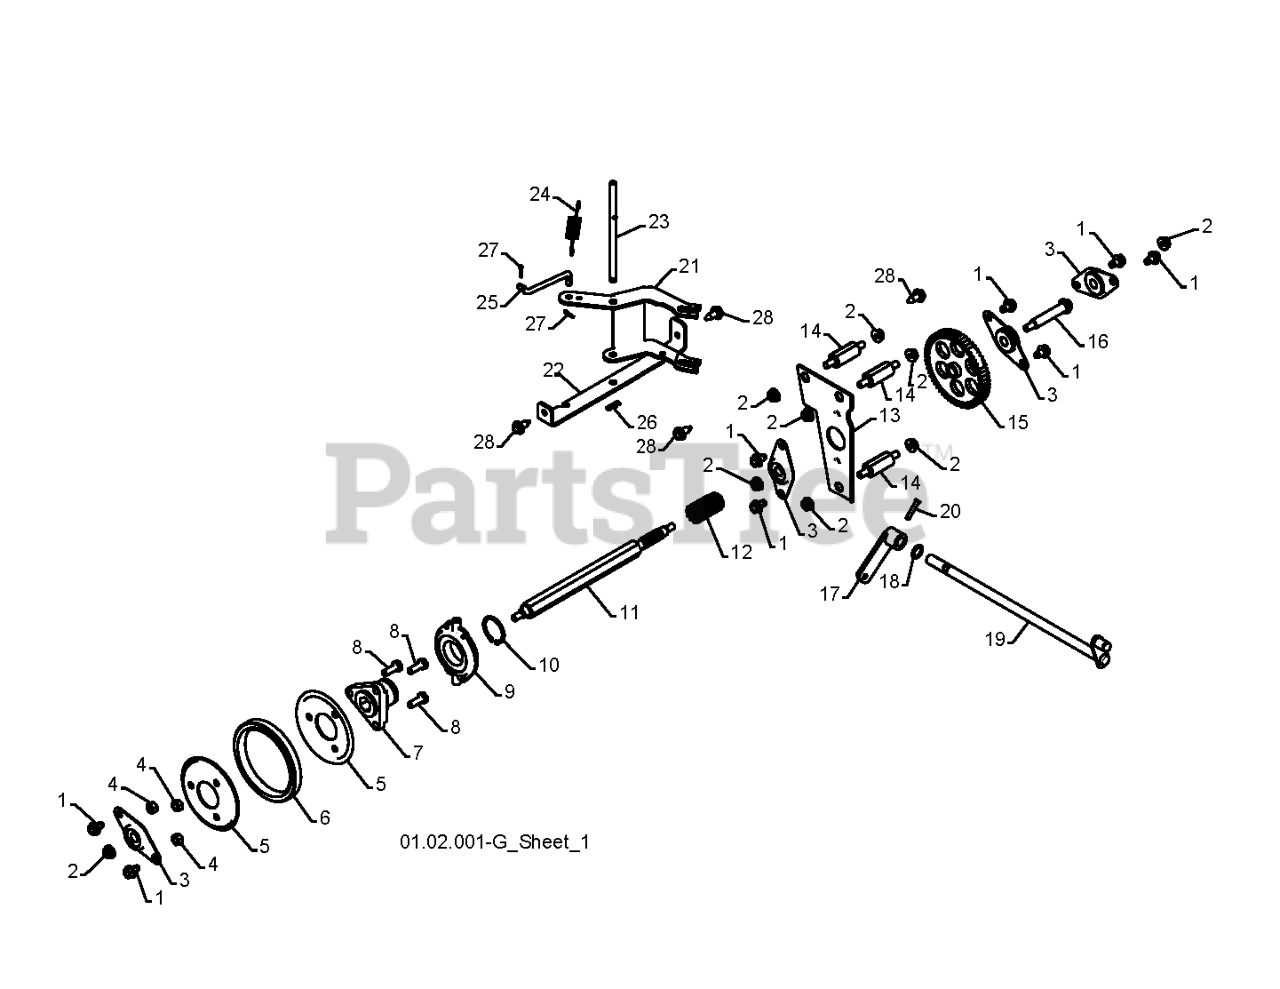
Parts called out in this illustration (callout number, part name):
1	Screw 5/16-18 x 1/2 Hex, Self Tapping 5/16-18 x 1/2
2	NUT.LOCK.5/16-18
3	BEARING, FLANGE
4	NUT.CENTERLOCK.5/16-
5	PLATE.RUBBER.WHEEL
6	RING, RUBBER WHEEL
7	HUB, RUBBER WHEEL
8	BOLT
9	TRUNNION BEARING ASSY
10	RETAINING RING (2 2)(3 2)
11	SHAFT.HEX.LONG
12	GEAR, PINION
13	AUXILLARY PLATE
14	SPACER, PLATE
15	GEAR, INTERMEDIATE
16	SHAFT, AUXILIARY
17	ARM, AUGER CONTROL
18	THRUST WASHER
19	SHAFT, AUGER CONTROL
20	CLEVIS PIN
21	LEVER, SPEED CONTROL
22	BRACKET, PIVOT, SHIFT
23	PIN, PIVOT
24	SPRING, BIAS
25	LINK, SPEED CONTROL
26	RETAINER CLIP PM
27	RETAINER CLIP
28	SELF-TAPPING SCREW 5/16-18X3/4
